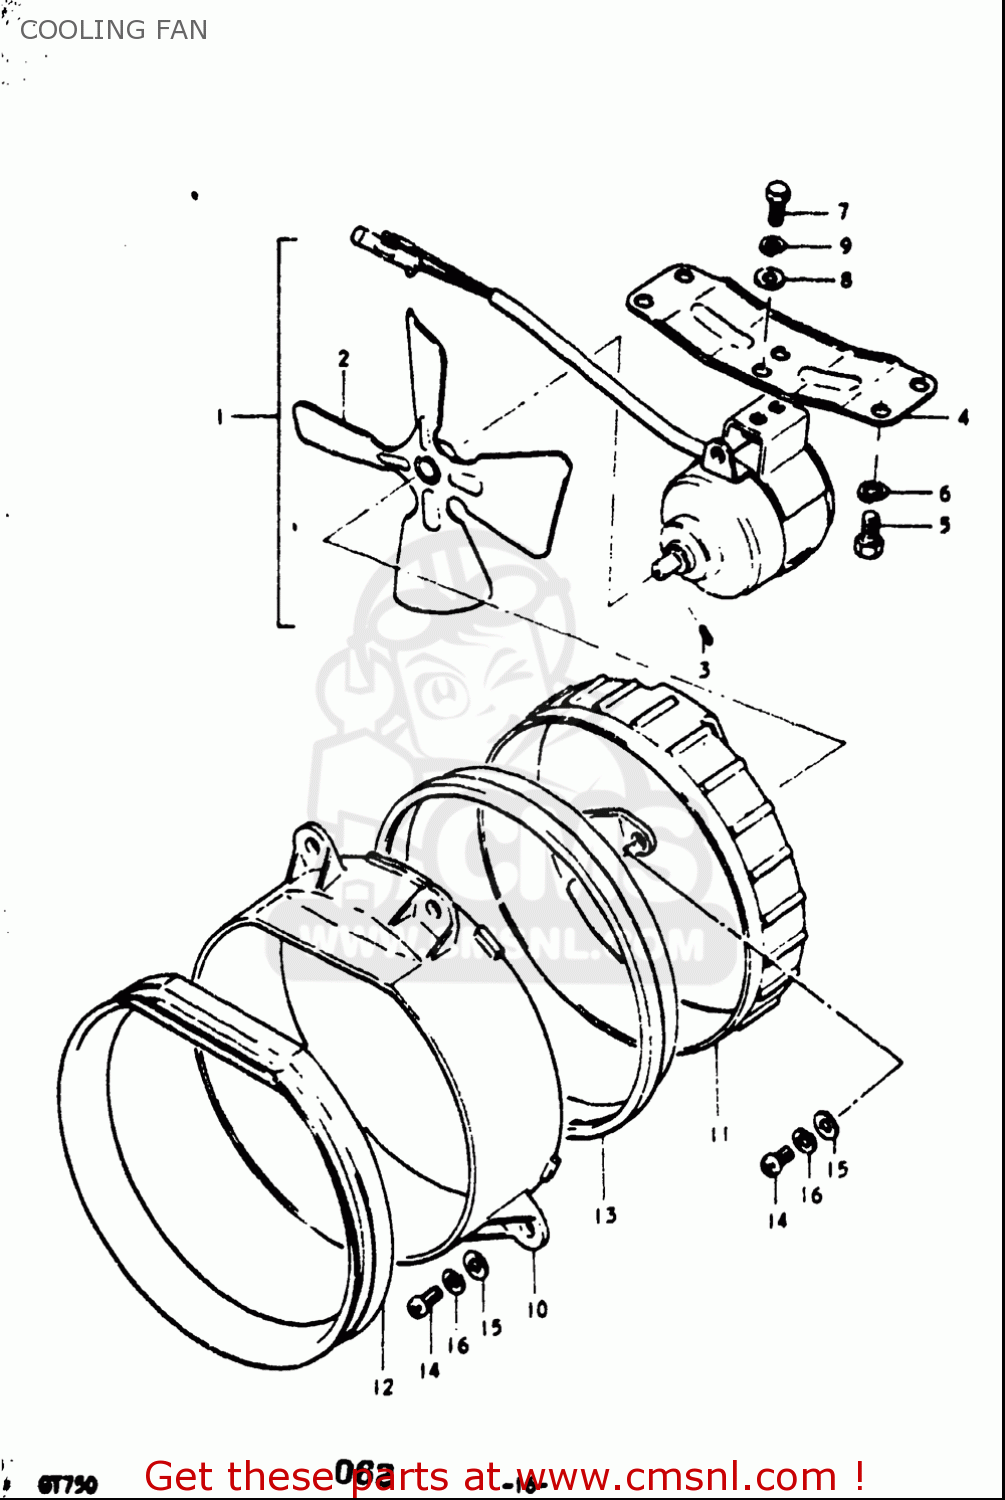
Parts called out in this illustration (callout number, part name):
3	SCREW
5	BOLT
6	WASHER,LOCK
7	BOLT
8	WASHER
9	WASHER,LOCK
14	SCREW
15	WASHER
16	WASHER,LOCK
